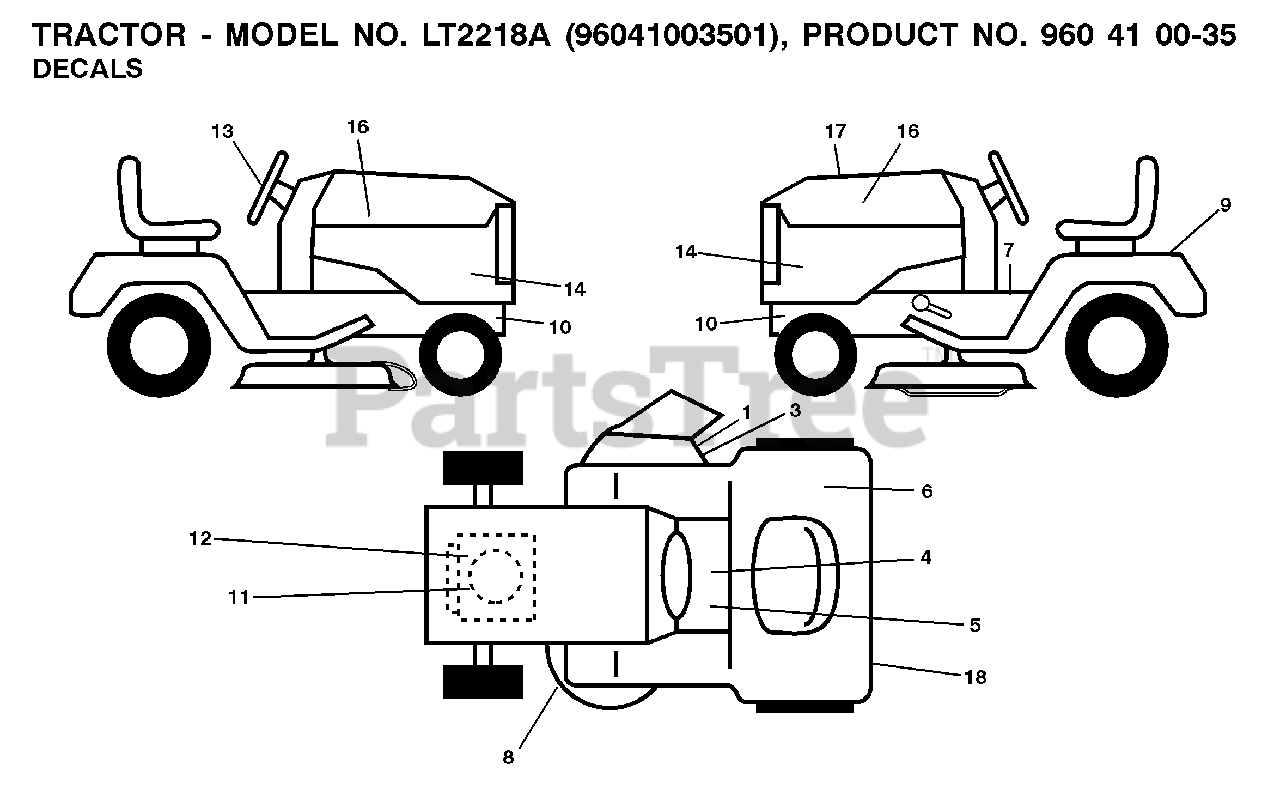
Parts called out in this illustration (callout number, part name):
1	DECAL.INTERNATIONL.CUTFINGER
3	DECAL, DEFLECT WARNING
4	DECAL PARK BRAKE
8	DECAL V BELT SCHEMATIC
9	DECAL BTRY SYMBOLS
